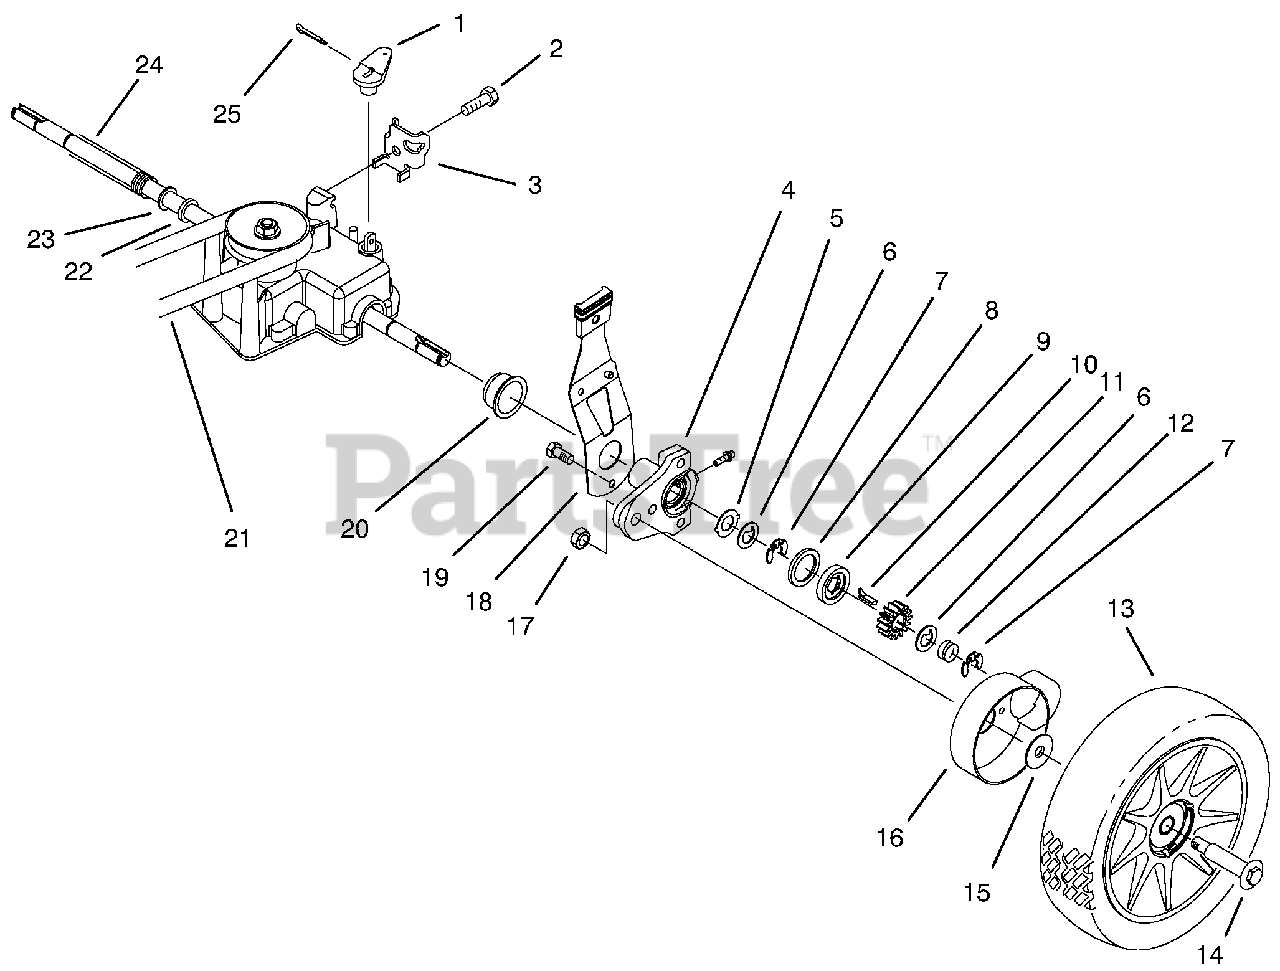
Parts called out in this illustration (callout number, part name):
1	Lever-Shift
2	Screw-Tapping
3	Retainer-Cable
4	Arm-Rear Height Adjust.
5	Washer-Thrust
6	Washer-Thrust Keyed
7	Ring-Retaining
8	Ring-Friction
10	Key-Rocking L.H.
11	Gear-Pinion
12	Spring-Compression
13	Wheel & Tire Assembly
14	Bolt-Shoulder
15	Washer-Stepped
16	Cover-Wheel
17	Nut-Lock
18	Spring Arm Assembly-L.H.
19	Screw-Hex Hd Tapping
22	Washer-Flat
24	Cover-Drive Shaft
25	Pin-Cotter
